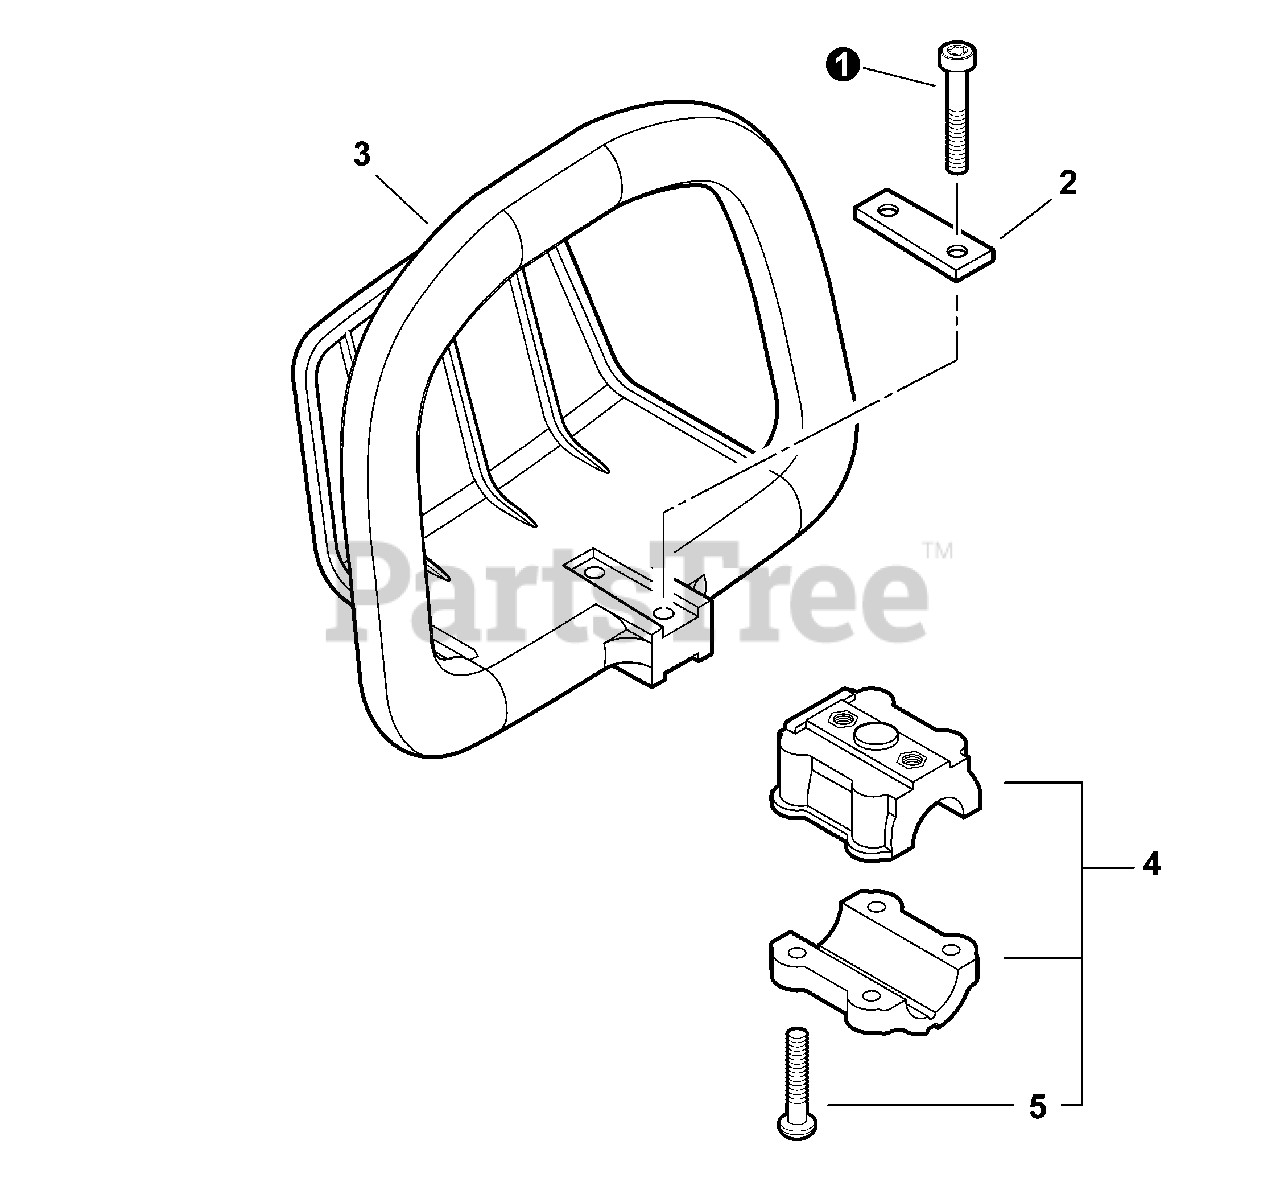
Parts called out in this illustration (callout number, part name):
1	BOLT, TORX 5×30
2	PLATE, EYE
3	HANDLE, SUPPORT
4	BRACKET KIT, HANDLE
5	BOLT, TORX 5×25
